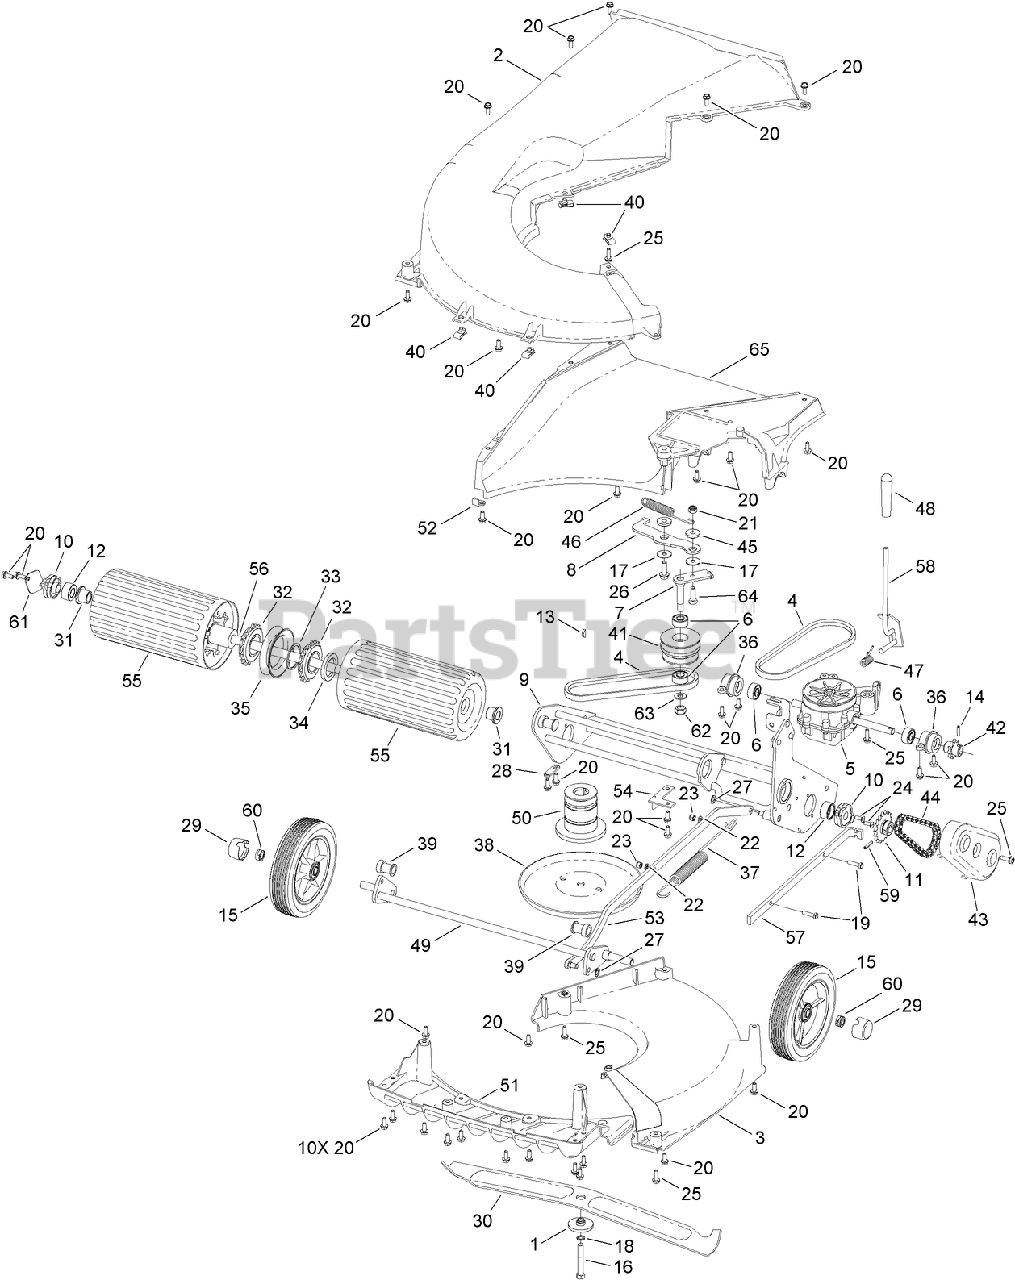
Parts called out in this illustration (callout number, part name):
1	SPACER-DISTANCE, CUTTERBAR
2	UNDERDECK-FIXED
3	UNDERDECK-REMOVABLE
4	BELT-VARIATOR (520)
6	BEARING
7	LEVER TAKE-UP ASM
8	ARM-PLATE, TAKE-UP
9	FRAME-ROLLER, REAR
10	BEARING-ROLLER
11	SPROCKET-18T
12	COVER-DUST, BUSHING
13	KEY-WOODRUFF
14	PIN-ROLL
15	WHEEL-RIBBED
16	BOLT-UNF
17	WASHER-PLAIN
18	WASHER-SPRING
19	SCREW-HH
20	SCREW-TAPTITE
21	NUT-HEX, NI
22	WASHER-PLAIN
23	NUT-NYLOC
24	SCREW-TAPTITE
25	SCREW-TAPTITE
26	SCREW-TAPTITE
27	WASHER-STARLOCK
28	PLATE-SECURING
29	CAP-HUB
30	CUTTERBAR
31	BUSHING-ROLLER, OILITE
32	FREEWHEEL-ROLLER
33	SPACER-STEEL
34	LOCKNUT
35	SHROUD-FREEWHEEL
36	HOUSING-PIVOT BEARING, LH
37	SPRING-COUNTER BALANCE
38	DISC-FRICTION
39	BEARING-AXLE, FRONT
41	PULLEY (TAKE-UP)
42	SPROCKET-GEARBOX
43	COVER-DRIVE
44	CHAIN-40 PITCHES (3/8 INCH LINK)
45	BUSHING-PIVOT
46	SPRING-VARIATOR
47	SPRING-TORSION, HOC
48	KNOB-HOC
49	AXLE-FRONT
50	BOSS-BLADE, CARRIER
51	FINS-FRONT
52	CLAMP
53	ROD-CONNECTING
54	BRACKET-ROD
55	ROLLER-REAR
56	SHAFT-ROLLER
57	BAR-TENSION, SPRING
58	LEVER-HOC
59	PIN-SPRING, SELLOC
60	NUT-UNF
61	PLATE-COVER, DUST
62	NUT-HEX, NI
63	WASHER-PLAIN
64	SCREW-HH
65	THROWPLATE
